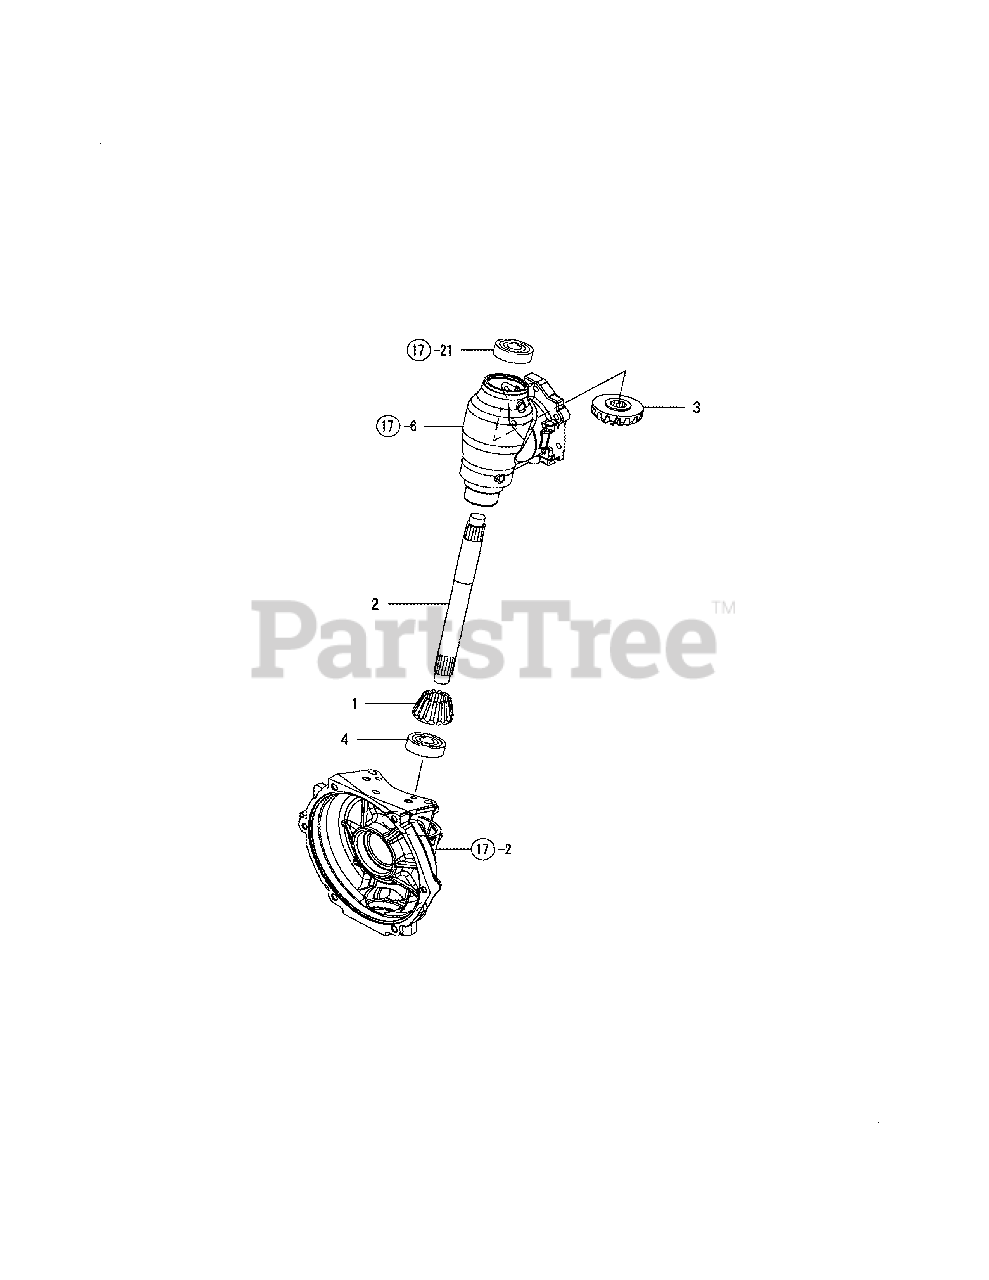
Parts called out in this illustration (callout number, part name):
1	PINION, FRONT FINAL
2	SHAFT, FRONT 2ND
3	GEAR FRONT 2ND Dia.=66MM
4	BEARING 304RSH2
